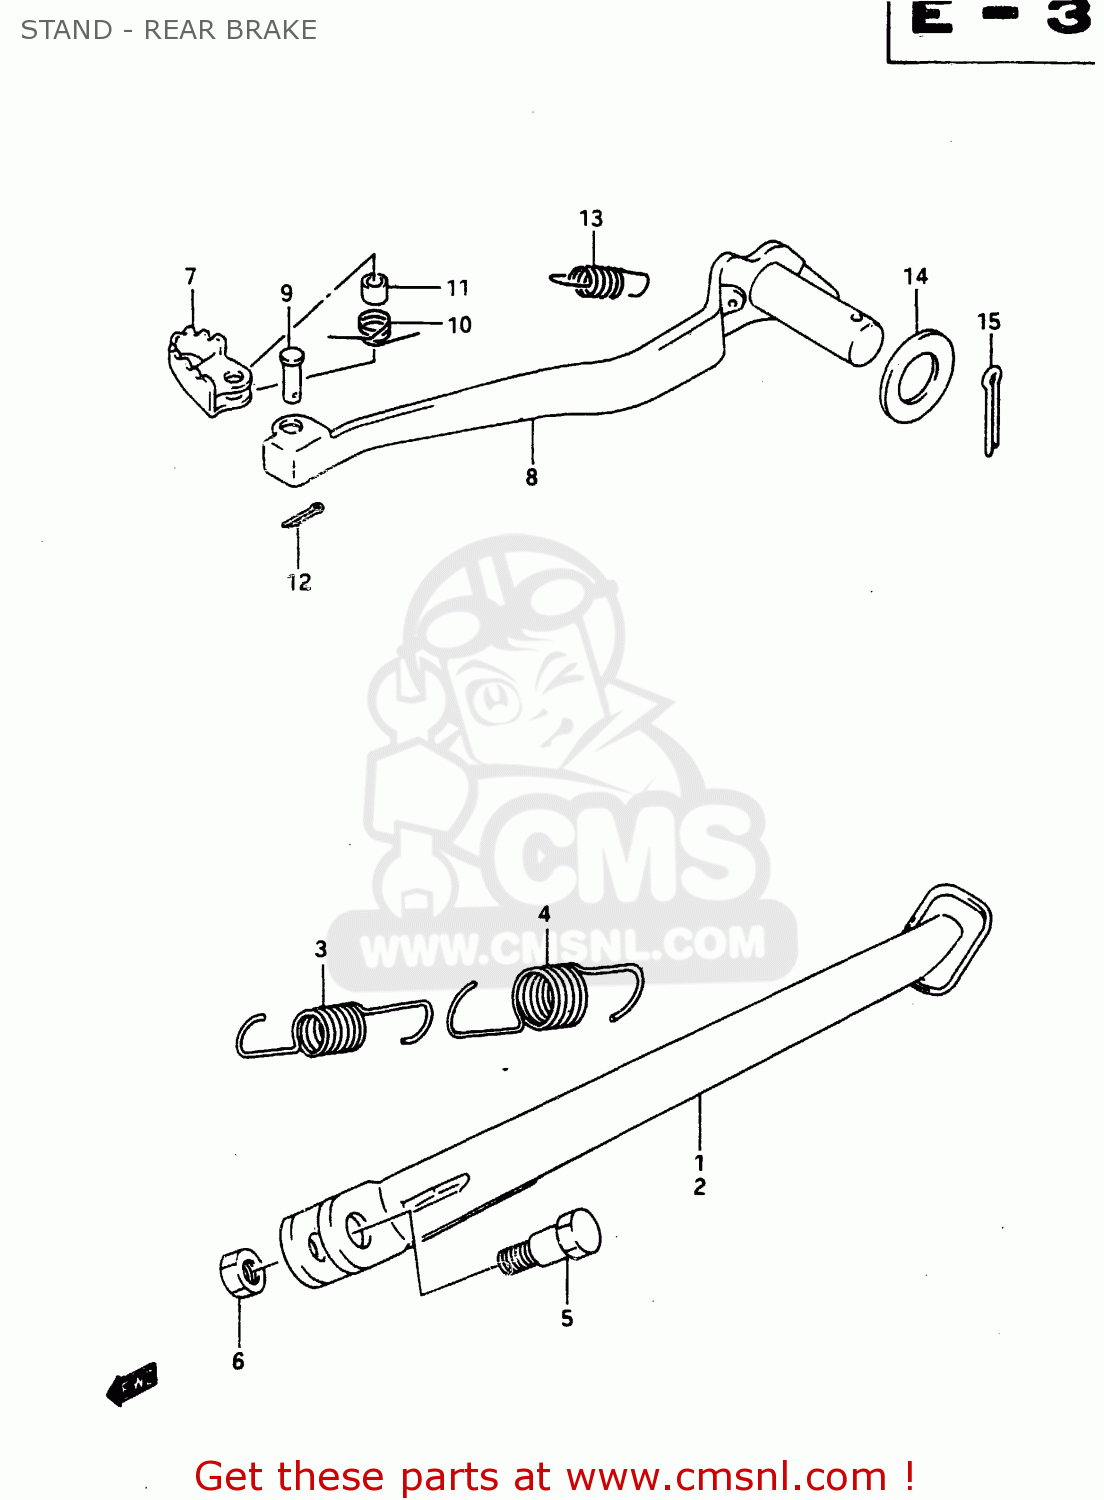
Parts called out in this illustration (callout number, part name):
1	STAND, PROP (BROWN)
2	STAND, PROP (BLUE)
3	SPRING
4	SPRING
5	BOLT(10X30)
6	NUT
7	PEDAL,BRAKE
8	ARM COMP,BRAKE PEDAL
9	PIN
10	SPRING
11	SPACER(9.2X9X6.5)
12	PIN
13	SPRING
14	WASHER (17.6X34X2)
15	COTTER PIN
